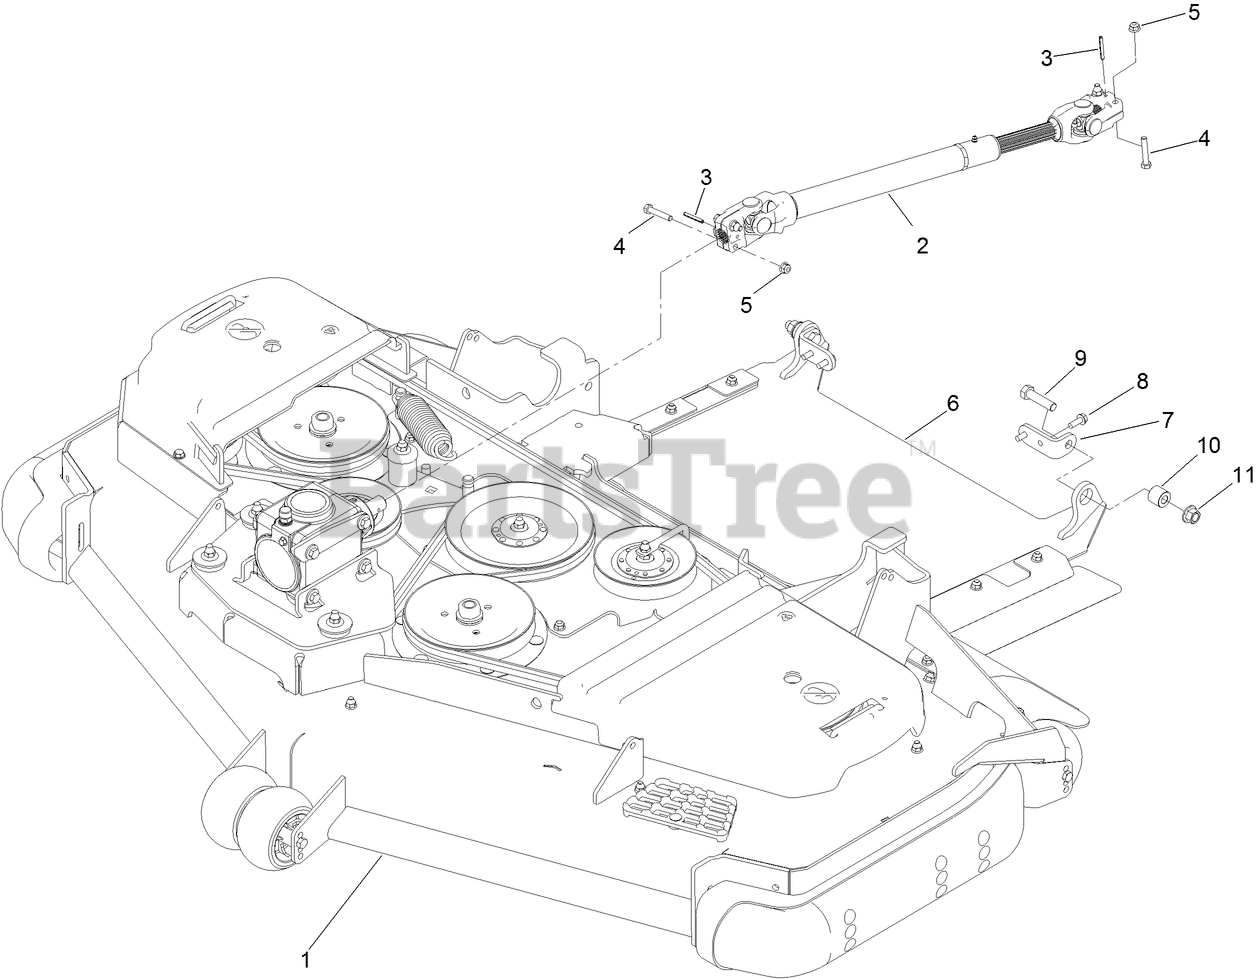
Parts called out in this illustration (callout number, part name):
2	DRIVESHAFT ASM
3	PIN-ROLL
4	SCREW-HH
5	NUT-HF, NI
6	DISCHARGE TUNNEL ASM
7	BRACKET-DISCHARGE
8	SCREW-TAPTITE
9	SCREW-HH
10	BUSHING-SLEEVE
11	NUT-LOCK
